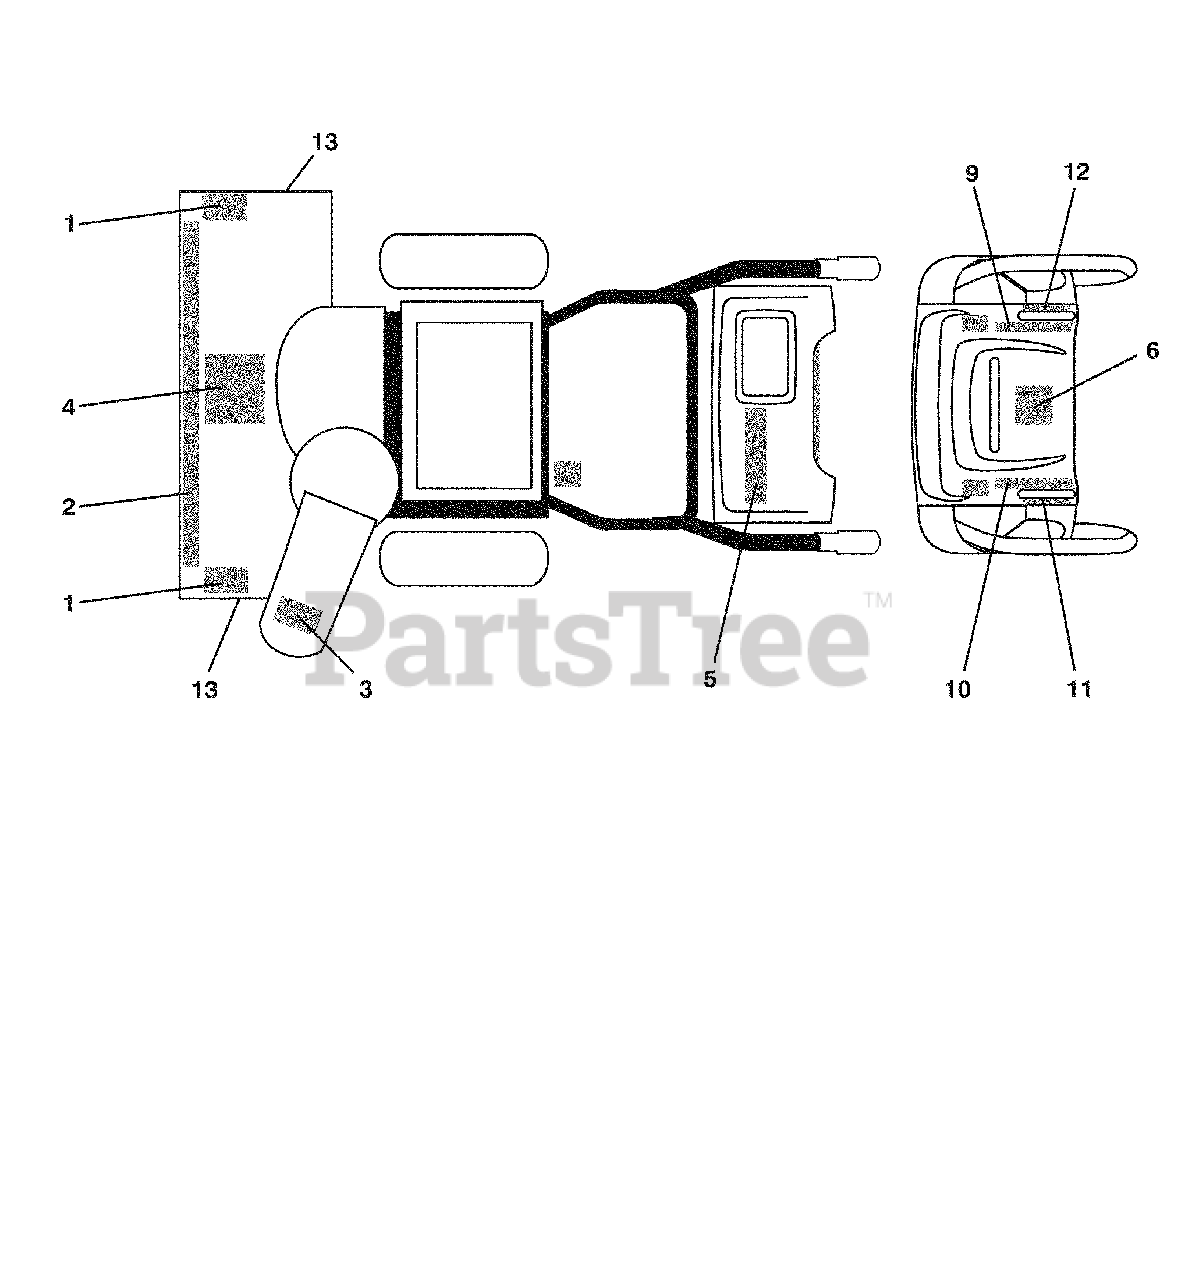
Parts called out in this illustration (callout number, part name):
1	Decal, Danger
2	Decal, Husqvarna
3	Decal, Danger, Deflector
4	Decal, Danger
5	Decal, Husqvarna, 1130SBEXP
6	Decal, Instruction
9	Decal, Auger Safety
10	Decal, Speed Control
11	Decal, LH Trigger
12	Decal, RH Trigger
13	Decal, Husqvarna, Crown
